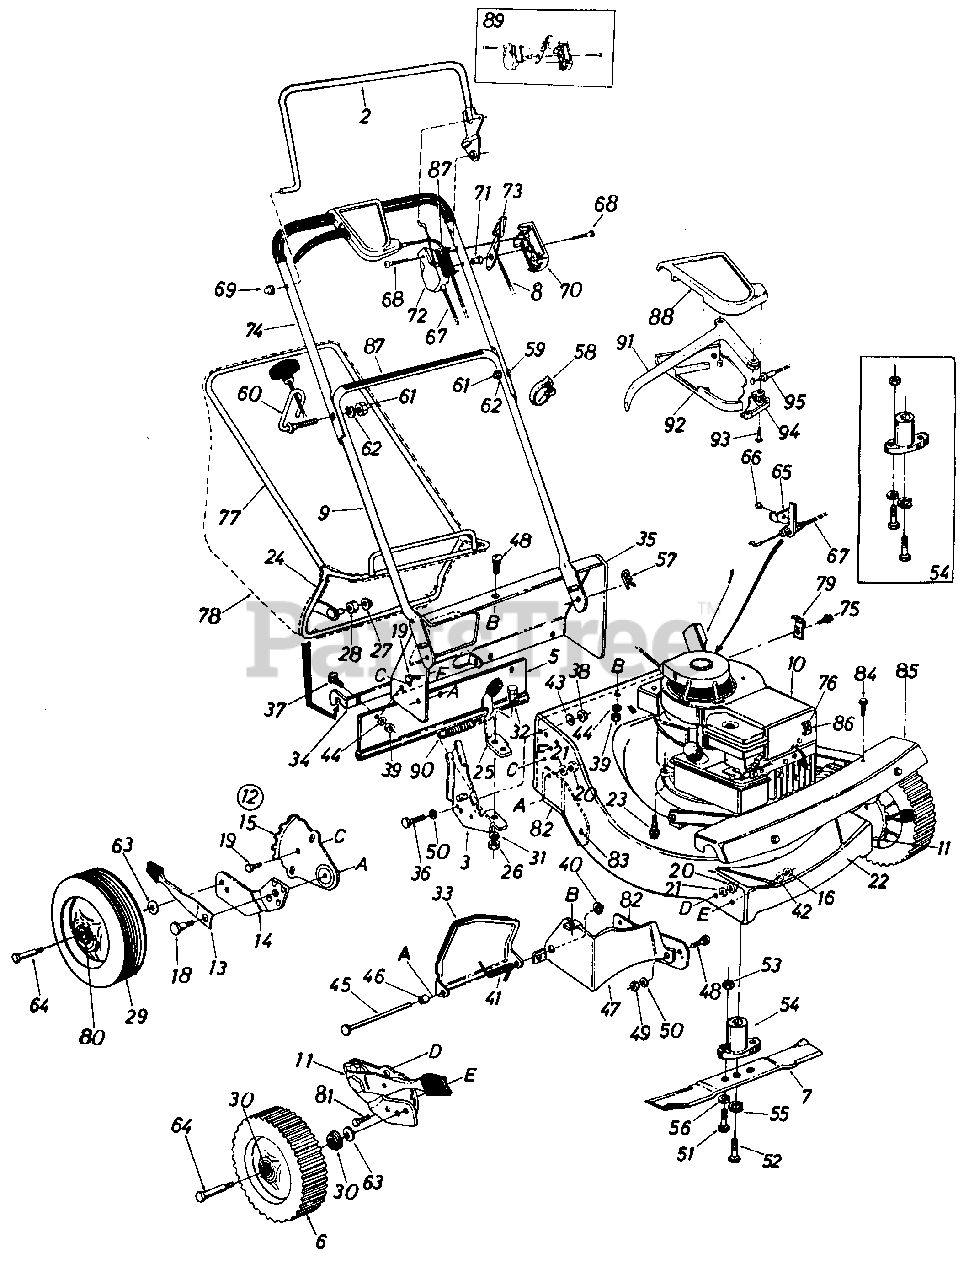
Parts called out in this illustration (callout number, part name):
1	Handle Brkt. Ass'y.-L.H.
2	Control Handle Ass'y.-L.H.
3	Handle Brkt. Ass'y.-R.H.
5	Rear Flap Ass'y.
6	Wheel Ass'y. Comp. 8 x 1.75
7	21" Blade
8	Throttle Wire-58.0"
9	Lower Handle
10	Engine
11	L.H. Height Adj. Ass'y.
12	R.H. Height Adj. Ass'y.
13	Spring Lever
14	Pivot Bar-L.H.
15	Index Plate
16	Hex Cent. L-Nut 3/8-16 Thd.
18	Shld. Bolt .500" Dia. x .430
19	Hex L-Wash. Hd. AB-Tap Scr. 1/4 x.62" Lg.
20	Hex Nut 3/8-16 Thd.
21	Bell-Wash. .39" I.D. x 1.38" O.D.
22	21" Deck Ass'y.
23	Self-Tap Screw 3/8-16 x 1.0"
26	Hex Nut 5/16-18 Thd.*
27	Push Nut 3/8" Rod
28	Plastic Roller
29	Wheel Ass'y. Comp. 8 x 1.75
30	Ball Bearing
31	L-Wash. 5/16" I.D.
32	Shld. Bolt .437" Dia. x .162
33	Chute Door
34	Grass Catcher Hitch Brkt.
35	Rear Discharge Deck Section
36	Hex Bolt 1/4-28 x .75" Lg.
37	Carr. Bolt 1/4-20 x .75" Lg.
38	Hex Nut 1/4-28 Thd.
39	Sems Nut 1/4-20 Thd.
40	Push Nut 1/4" Rod
41	Torsion Spring
42	L-Wash. 3/8" I.D.
43	Bell-Wash. 1/4" I.D. x .88" O.D.
44	Fl-Wash. .285" I.D. x 1.25" O.D.
45	Hinge Pin .250" Dia. x 7.25"
46	Spacer .262" I.D. x .31" O.D. x .58
47	Rear Baffle
48	Carriage Bolt 1/4-20 x .50"
49	Hex Nut 1/4-20 Thd.
50	L-Wash. 1/4" I.D.
51	Hex Bolt 5/16-24 x 1.00" Lg. (Grade 5)
52	Hex Bolt 3/8-24 x 2.25" Lg. (Grade 5)
53	Hex Nut 5/16-24 Thd.
54	Blade Adapter Kit
55	L-Wash. 3/8" I.D.-H.D.
56	L-Wash. 5/16" I.D.
57	Intern. Cot. Pin 5/16" Dia.
58	Cable Tie
59	Curved Carriage Bolt 5/16-18 x 1.38" Lg.
60	Rope Guide Bolt
61	Hex Nut 5/16-18 Thd.
62	L-Wash. 5/16" I.D.
63	Bell-Wash. .400" I.D. x .88" O.D. x .060
64	Axle Bolt
65	Cable Bracket
66	Pop Rivet .156" Dia. x .379
67	Brake Control Cable-43.0"
68	Truss Mach. Hd. "B" Tap Scr. #12 x 1.50" Lg.
69	Cap Speed Nut 5/16" Rod
70	Control Panel Half
71	Control Disc Pin
72	Control Panel Half
73	Throttle Control Lever
74	Upper Handle
75	Hex AB-Tap Scr. #10 x .38"
76	Casing Clamp
77	Grass Catcher Upper Frame
78	Grass Bag
79	Casing Clamp
80	Fortiflex Bearing
81	Hex Bolt 3/8-16 x .75" Lg.
82	Side Baffle
83	Rivet
84	Hex Wash. Hd. Self-Tap Scr. 1/4-20 x .50" Lg.
85	Drive Cover
86	Hex Wash. Hd. AB-Tap Scr. #8 x .38" Lg.
87	Instruction Labels
88	Control CoverTop Half
89	Kit-Control Housing Complete
90	Extension Spring
91	Control Lever
92	Control Cover-Bottom Half
93	Fl-"C" Sunk Hd. Scr. #10 x .75" Lg.
94	Cable Mounting Cap
95	Self-Propelled Cable
